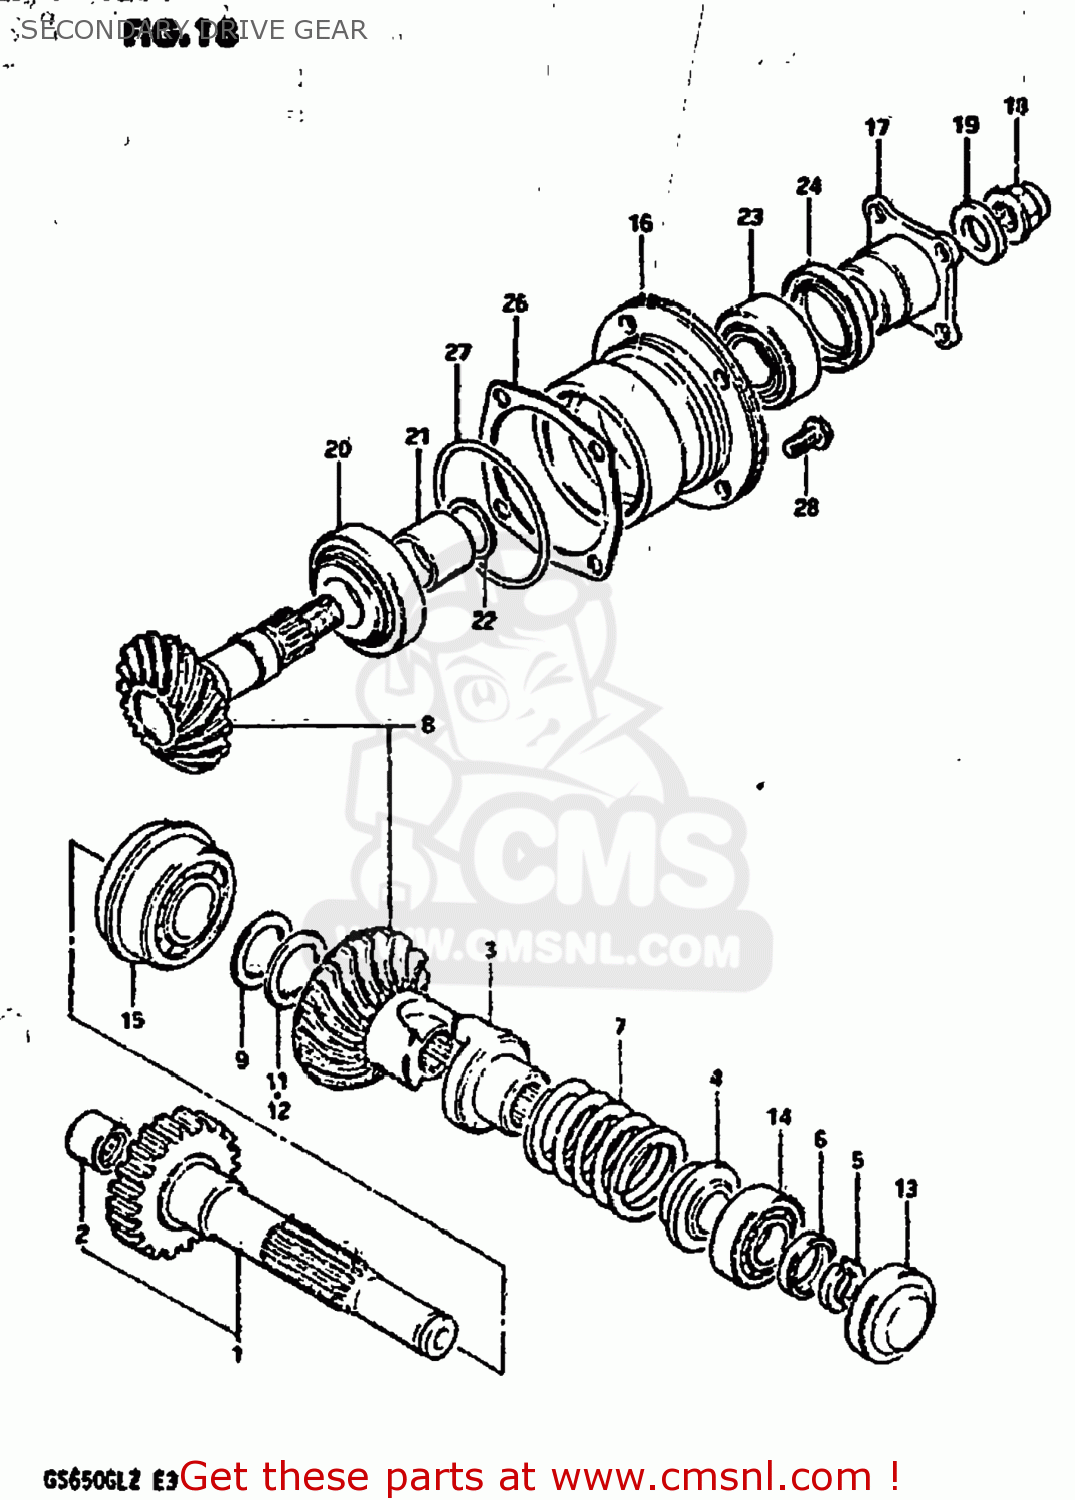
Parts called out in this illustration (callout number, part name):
1	SHAFT,OUTPUT
2	BEARING(15X23X20)
3	DOG
4	STOPPER
5	STOPPER,CAM DOG
6	HOLDER,CAM DOG STOPPER
7	SPRING
8	SECONDARY GEAR SET
9	SHIM,SECONDARY DRIVE
10	SHIM SET,SECONDARY DRIVE BEVEL
11	SHIM,SECONDARY DRIVE BEVEL
12	SHIM,SECONDARY DRIVE BEVEL
13	PLUG
14	BEARING(20X47X14)
15	BALL BEARING 30X62X24
16	HOUSING,SECONDARY DRIVE
17	FLANGE,UNIVERSAL JOINT
18	NUT
19	WASHER(14X29X4)
20	TAPER,ROLLER BEARING
21	SPACER (25.2X30X40)
22	SHIM (25X30X2
23	BEARING
24	SEAL,OIL(35X52X9)
25	SHIM SET,SECONDARY DRIVE
26	SHIM,DRIVEN GEAR HOUSING
27	O RING(D:3.1,ID:69.4)
28	BOLT
